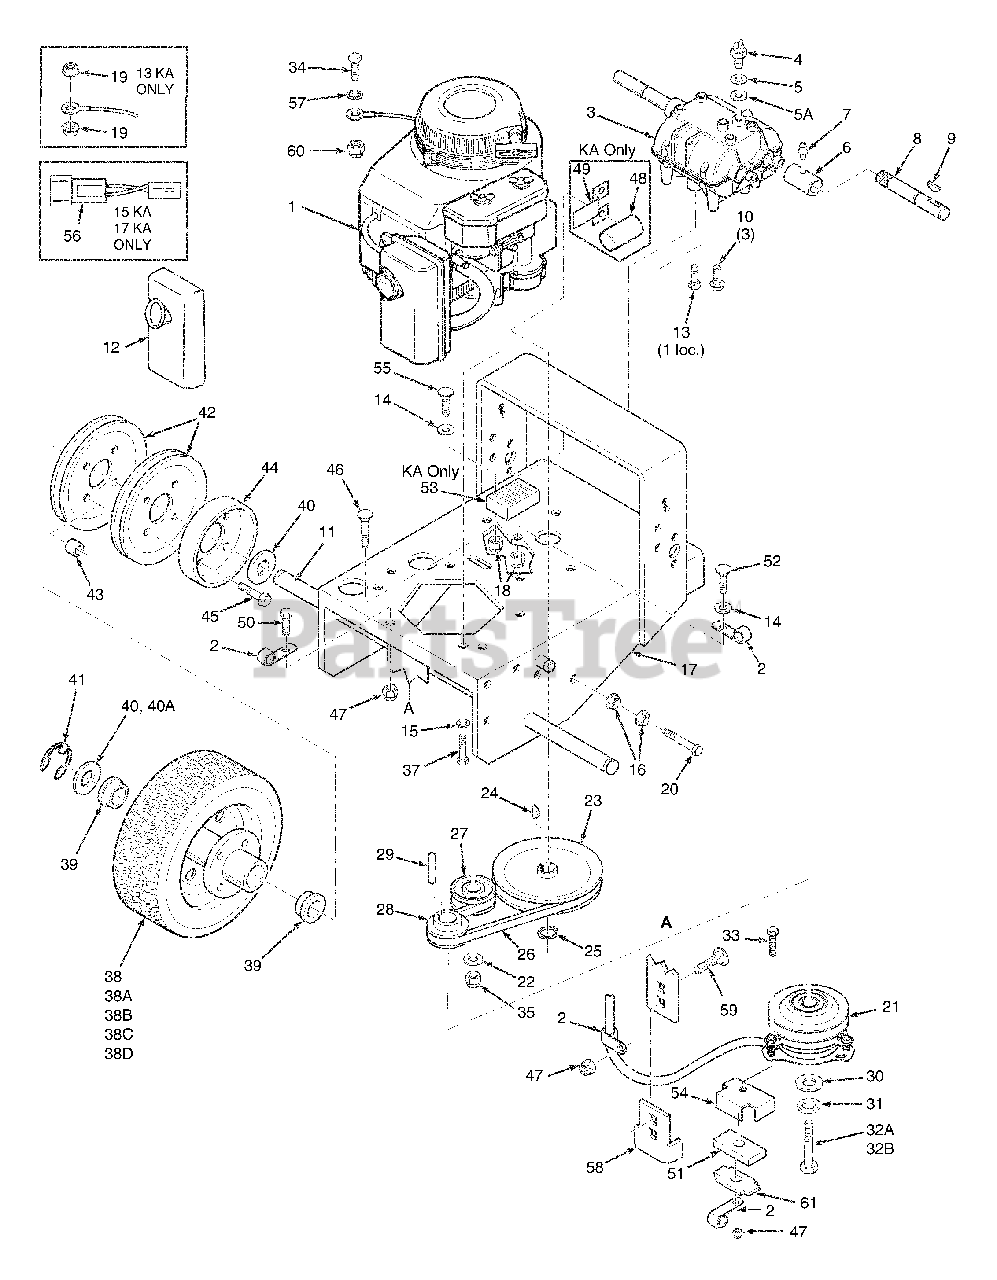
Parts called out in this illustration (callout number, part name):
1	Engine, 15HP Kawasaki (Spec FH451V-AS09)
2	Cable Clamp
3	Transmission, 5-speed
4	Neutral Safety Switch
5	Fibre Washer, thin
5A	Fibre Washer, thick
6	Coupler, Jackshaft
7	Grease Fitting, straight 1/4-28
8	Jackshaft (fits SW32,36,48 & 52)
9	Key, Hi-Pro #9
10	Bolt, 5/16-18 X 3/4" Carriage
11	Wheel Axle (SW36,48 & 52)
12	Muffler
13	Bolt, 5/16-18 X 3/4" Hex Head
14	Flat Washer 1/4" (.312 X .75 X .065)
15	Lock Wshr. 5/16"
16	Nut, 3/8-16 Serrated Flange
17	Engine Deck (fits SW36,48 & 52)
18	Nut, 1/4-20 Elastic Stop
19	Nut, 5/16-18 Serrated Flange
20	Bolt, 3/8-16 x 3-3/4" Hex Head
21	Electric Clutch (Ogura)
22	Washer, 3/8" (.391 x .938 x .105)
23	Pulley, Transmission Input
24	Key, Woodruff #9
25	Retaining Ring, 5/8" Ext, Basic
26	Belt, Transmission Drive
27	Idler Pulley, Transmission
28	Pulley, Traction Drive
29	Key, 1/4 x 1/4 x 3/4"
30	Flat Washer, 7/16" Special
31	Lock Washer, 7/16"
32A	Bolt, 7/16-20 x2-1/2" Hex Head
33	Bolt, 5/16-18 x 1-3/4" Hex Head
35	Nut, 3/8-16 Elastic Stop
36	Flat Washer, 5/16"
38	Wheel Assembly (fits SW36,48,52)
38A	Tire, 13 x 6.50-6, 2-ply (fits SW36,48,52)
38B	Rim & Bearing Assembly (fits SW36,48,52)
39	Wheel Bearing (OD 2.000 - 2.005)
40	Washer, 1-1/16 x 1-3/4 x 12 ga
40A	Washer, 1-1/16 x 1-1/2 x 18 ga
41	Retaining Ring, 1" Ext.- "E"
42	Pulley, Wheel Drive
43	Spacer, Wheel Pulley
44	Brake Drum
45	Bolt, 5/16-18 x 1-1/2" Serrated flange
46	Bolt, 3/8-16 x 2" Carriage
47	Nut, 5/16-18 Elastic Stop
50	Bolt, 5/16-18 x 1" Hex Head
51	Rubber Pad, Clutch Stop
52	Bolt, 1/4-20 x 3/4" Carriage
54	Backing Plate
56	Wire Harness Adapter (15KA & 17KA)
57	Lock Washer Internal Tooth
58	Anti Rotation Bracket
59	Bolt, 5/16-18 x 1" Carriage
60	Nut, 1/4-20 Elastic Stop
61	Plate, Backing
